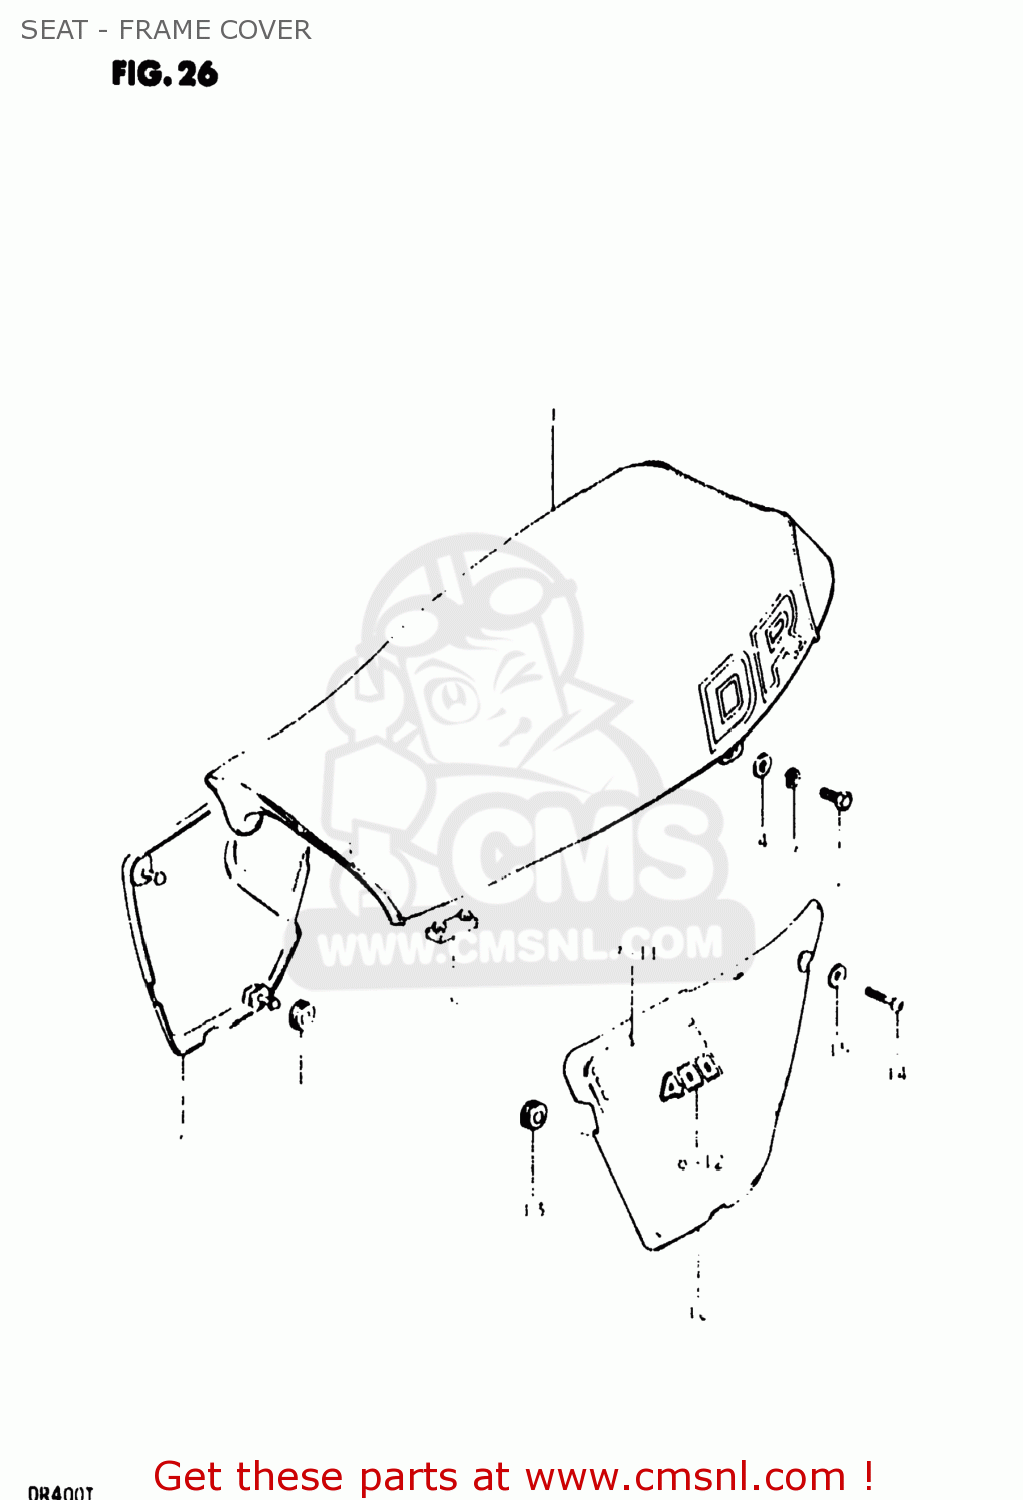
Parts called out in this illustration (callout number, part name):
1	SEAT ASSEMBLY
2	BOLT
3	LOCK WASHER
4	WASHER
5	CUSHION
6	COVER,FRAME,RIGHT
7	TAPE,FRAME COVER,RIGHT STRIPE
8	EMBLEM
9	CUSHION
10	COVER,FRAME,LEFT
11	TAPE,FRAME COVER
12	EMBLEM (400)
13	CUSHION
14	SCREW
15	WASHER
